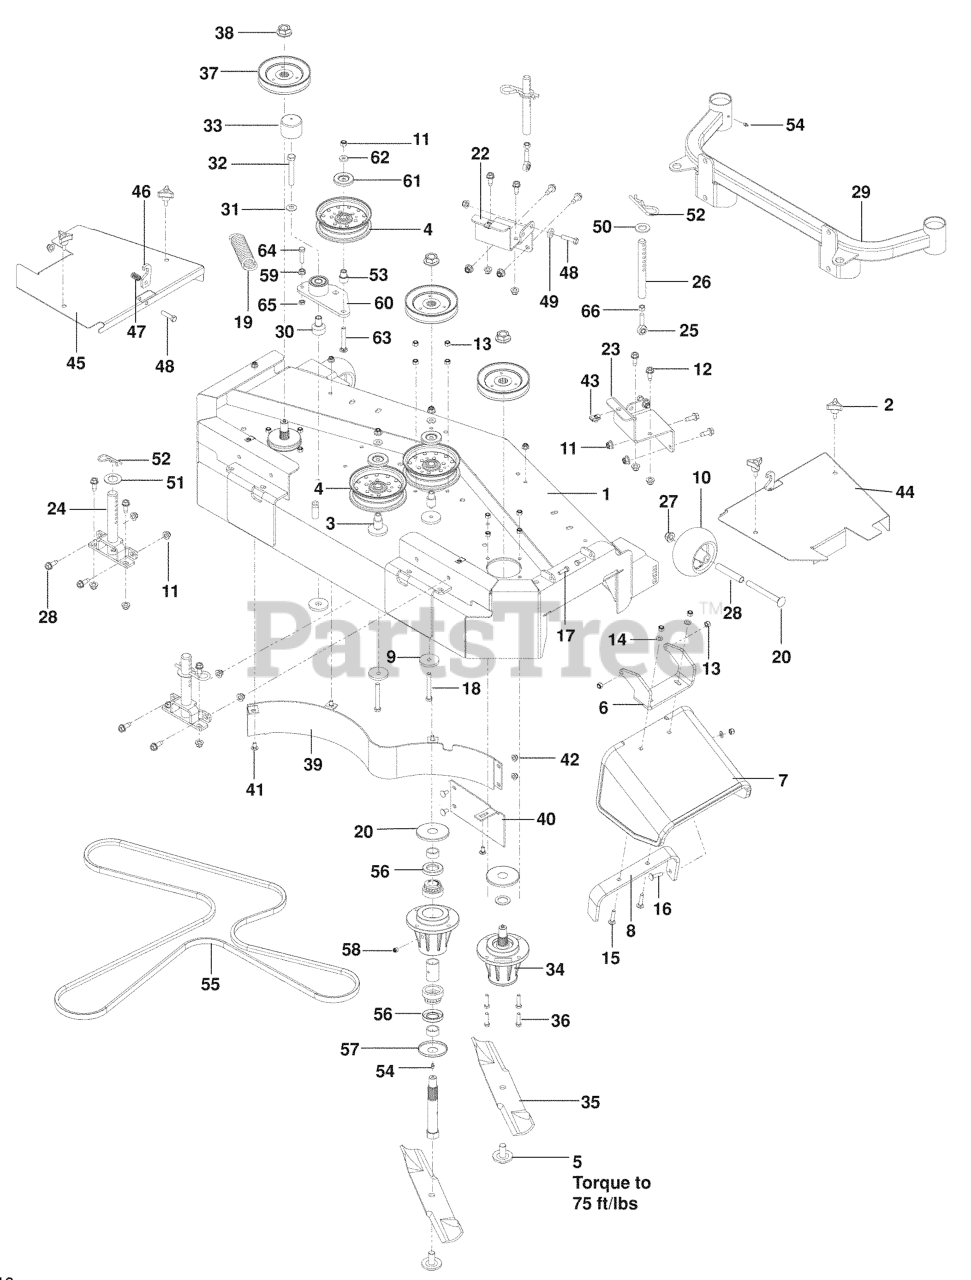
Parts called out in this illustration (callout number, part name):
1	CUTTER DECK 48" W/DECALS
2	KNOB W/STUD
3	IDLER BUSHING
4	IDLER PULLEY
5	BLADE BOLT/WASHER
6	HINGE CHUTE - BLACK
7	CHUTE, RUBBER DISCHARGE WB
8	BRKT, REINF-CHUTE WB
9	SPINDLE WASHER
10	ROLLER, GAUGE .635 BORN
11	NUT 3/8-16 HEX FLG NYLOC ZD
12	BOLT 3/8-16 X 1.0
13	NUT 5/16 NYLOC
14	FLAT WASHER 5/16 SAE
15	RHSNB 5/16-18 X 1-1/2 GR 5 ZD
16	BOLT, CARRIAGE 5/16X1-1/4
17	HCS 5/16C X 1
18	HCS 3/8C X 3
20	RHSNB 1/2-13 X 4.75 GR5 ZD
21	MACHINE BUSHING
22	SUPPORT - FRONT, LH
23	SUPPORT - FRONT, RH ORANGE
25	ROD END - 3/8-24 RH
27	NUT, 1/2-13 HEX FLG NYLOC ZD
28	TUBE, ROLLER AXLE
29	SUPPORT, CASTER 48 OR
30	PIVOT, BEARING
31	CONTACT BELLSPR 1/2
32	HCS 1/2C X 3 1/4
33	CAP, VINYL
34	HOUSING ASM, 72
35	BLADE OEM 16 1/4"
36	HCS 5/16C X 1 1/4
37	PULLEY - 5.25
38	NUT FLANGE 3/4-16
39	BAFFLE WLDT, BLACK
40	CENTER BAFFLE 48"
41	CARRIAGE BOLT 5/16C X 5/8"
42	5/16-18 NYLOC FLANGE NUT
43	U-CLIP 5/16-18 NUT RETAINER
44	COVER, 48 RH GY
45	COVER, 48 LH GY
47	SPRING - COMPRESSION
48	HCS 3/8C X 1 1/2
49	WASHER 3/8 X 3/4 X .187 TK
50	WASHER 3/4 FLAT SAE ZD
53	BUSHING, IDLER
54	ZERK
55	BELT, 134.5
56	SHAFT SEAL
57	BOTTOM DUST CAP
58	PLUG-VENTED
59	NUT 3/8C WHIZ
60	ARM-IDLER W/BRG
61	DUST SHIELD
62	WASHER, 3/8 THICK
63	RHSNB 3/8-16 X 2.75
64	HCS 3/8-16 X 1-1/2
65	NUT 3/8-16 HEX JAM
